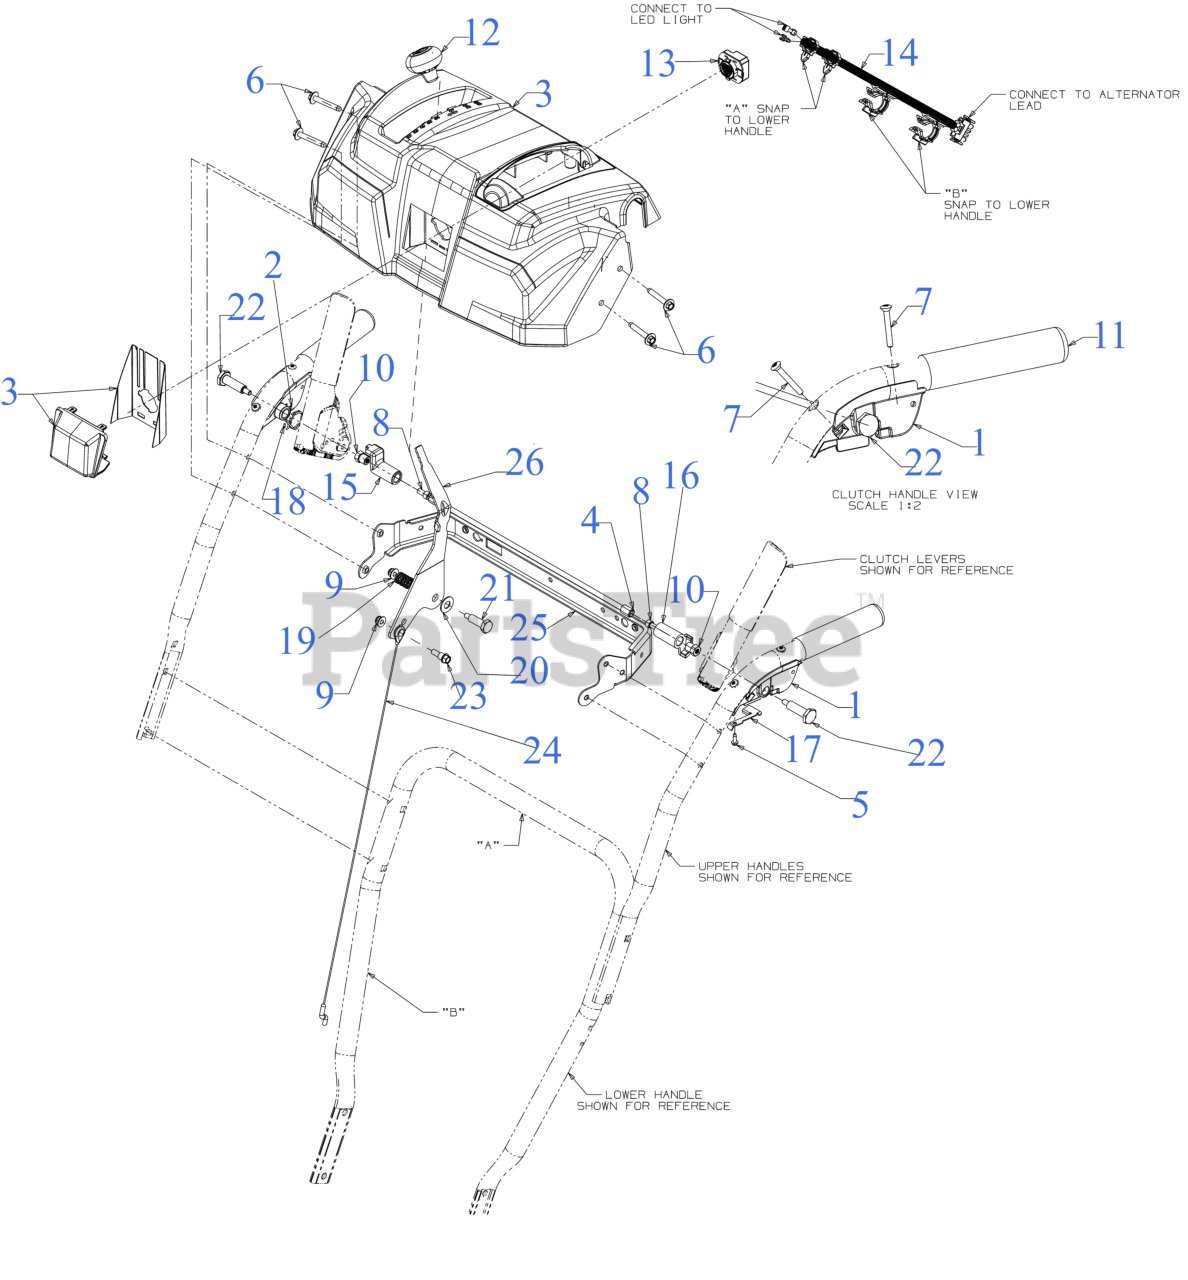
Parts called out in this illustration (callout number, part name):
1	CLUTCH LOCK HANDLE ASSEMBLY (LH)
2	CLUTCH LOCK HANDLE ASSEMBLY (RH)
3	HANDLE PANEL ASSEMBLY
5	SCREW #8-16 x .50
6	SCREW 1/4-20 x 1.625
7	SCREW #10-24 x 1.375
8	SCREW 1/4-20 x .50
9	FLANGE LOCK NUT
10	HEX NUT W/PATCH
12	SHIFT KNOB
13	LED HEADLIGHT & SOCKET (150 LUMNES)
14	LIGHT HARNESS
16	CLUTCH LOCK CAM
17	CLUTCH SPRING
18	TORSION SPRING
19	COMPRESSION SPRING
20	FLAT WASHER .38X.88
21	SHOULDER SCREW
22	SHOULDER SCREW .437 x 1.345 1/4-20
23	SHOULDER SCREW .342X.335X1/4-20
24	SELECTION CABLE
24	SPEED SELECTOR CABLE (PLASTIC)
